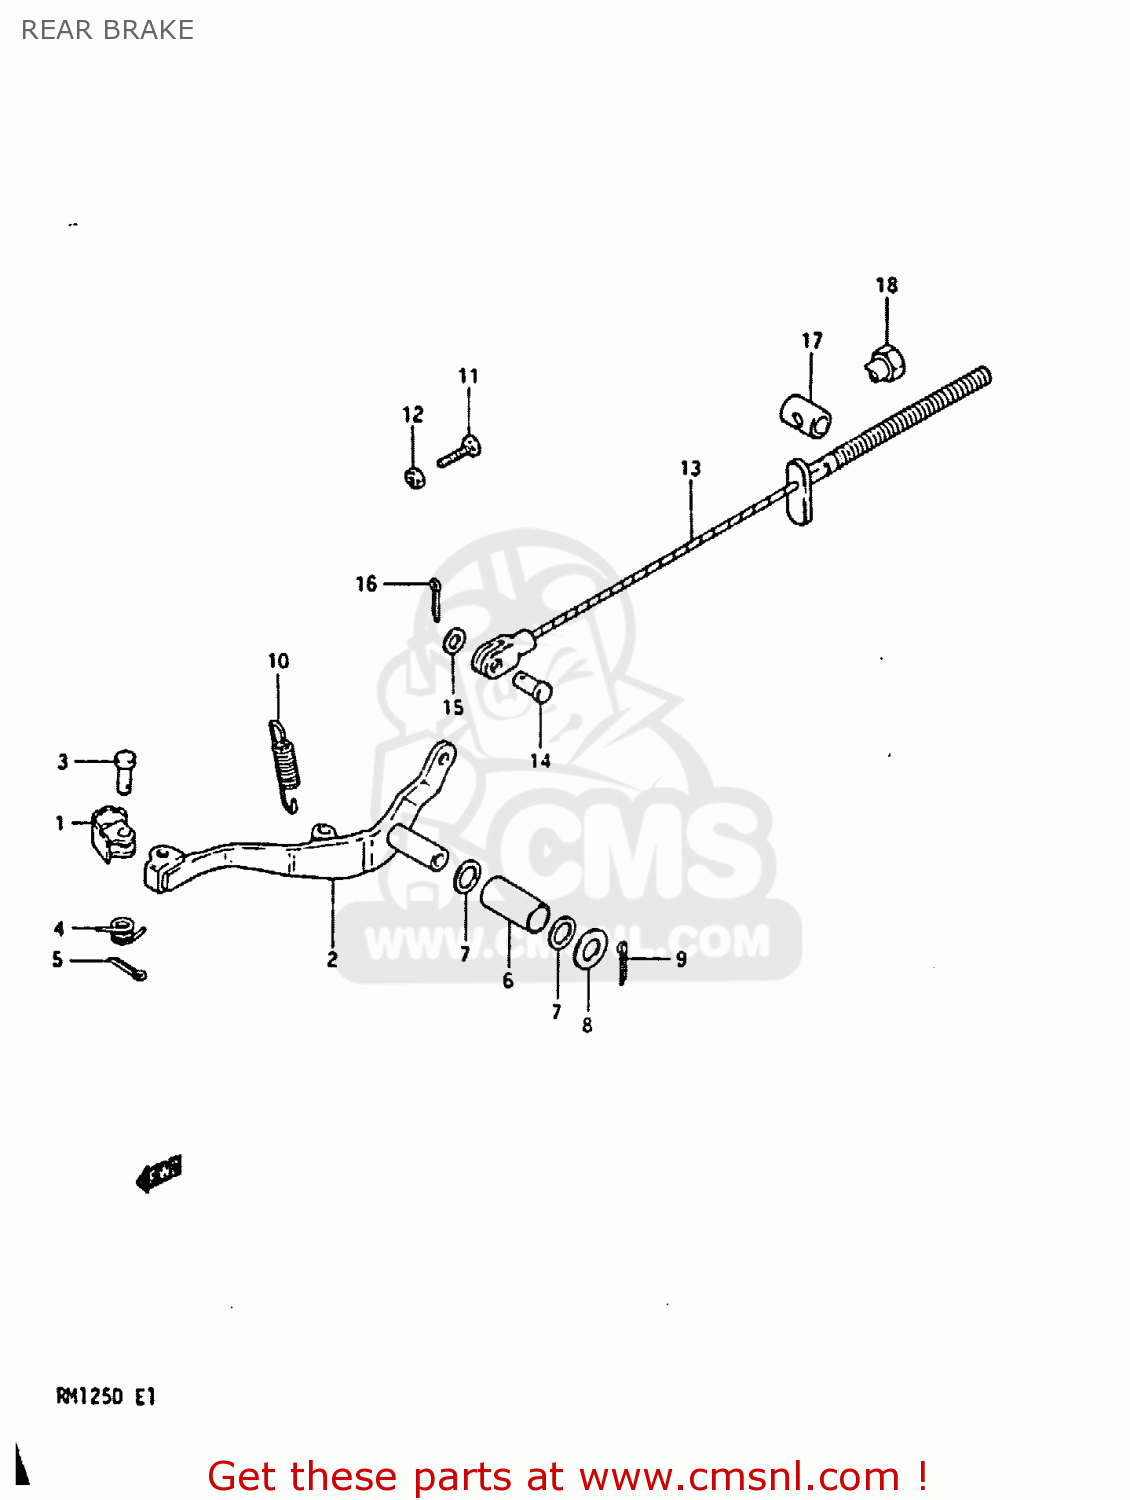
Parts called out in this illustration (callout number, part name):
1	PEDAL,BRAKE
2	ARM,BRAKE PEDAL
3	PIN
4	SPRING
5	PIN
6	BUSHING
7	O RING(D:2.2,ID:11.8)
8	WASHER
9	PIN 30X20
10	SPRING
11	SCREW(6X23)
12	NUT
13	CABLE,RR BRAKE
14	PIN(L:17.5)
15	WASHER
16	PIN 20X20
17	PIN
18	NUT (6MM)
